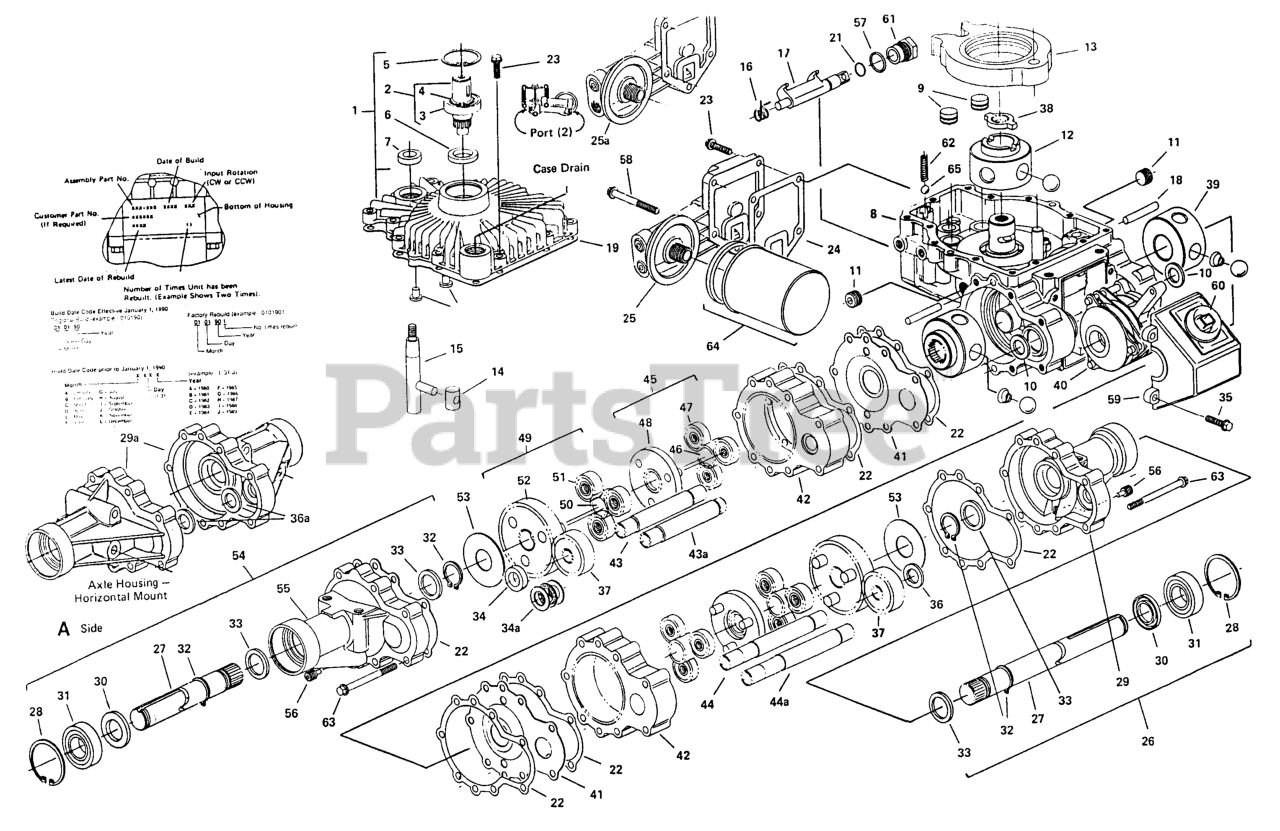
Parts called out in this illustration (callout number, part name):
3	Bearing, Input Shaft
4	Ring, Retaining, External
5	Internal Retaining Ring
6	SEAL,INPUT SHAFT
7	SEAL,CONTROL SHAFT
8	Housing, S/A Cw
9	Piston, Dampening, S/A
13	Cam Ring, S/A
15	Control Shaft, S/A
16	DUMP VALVE SPRING
19	COVER GASKET
23	Screw, 1/4-20 Hex Flange
25	FILTER BASE S/A
25A	Filter Base, S/A W/Auxiliary Ports (2)
26	Axle Housing, S/A-B
27	Shaft, Axle
28	Internal Retaining Ring
29A	Housing, Axle B
32	External Retaining Ring
33	THRUST WASHER
34	Spacer (Thick-Pb)
34A	Washer, Thrust (Dl/Pb)
34A	Bearing, Thrust (Dl/Pb)
35	Screw, 1/4-20 Self Tap
36	Spacer (Thin-Pb Or Dl/Pb)
36A	Spacer (Thick) Used With Vertical Mount Housing
39	MOTOR ROTOR BALL
41	WEAR PLATE
42	A&B RING GEAR 5/A57T
43A	Brake Shaft-A (Dl/Pb)
44	BRAKE SHAFT B
44A	Brake Shaft-B (Dl/Pb)
46	Sun Gear, First, 15t
47	Plnt Gear, First, A & B S/A, 21t
48	Primary Carrier, A & B S A, 15t
50	Sun Gear, Second, 15t
51	Pint Gear, Second, A & B S A, 21t
52	Secondary Carrier, A & B S
53	Washer, Thrust
54	Axle Housing, S/A-A
56	MAGNETIC PLUG
57	Dump Valve Nut, O-Ring
58	Screw, 1/4-20 Hex Flange
59	PARKING BRAKE COVER
63	Screw, 1/4-20 Hex Flange
64	Filter, (W/Seal)
